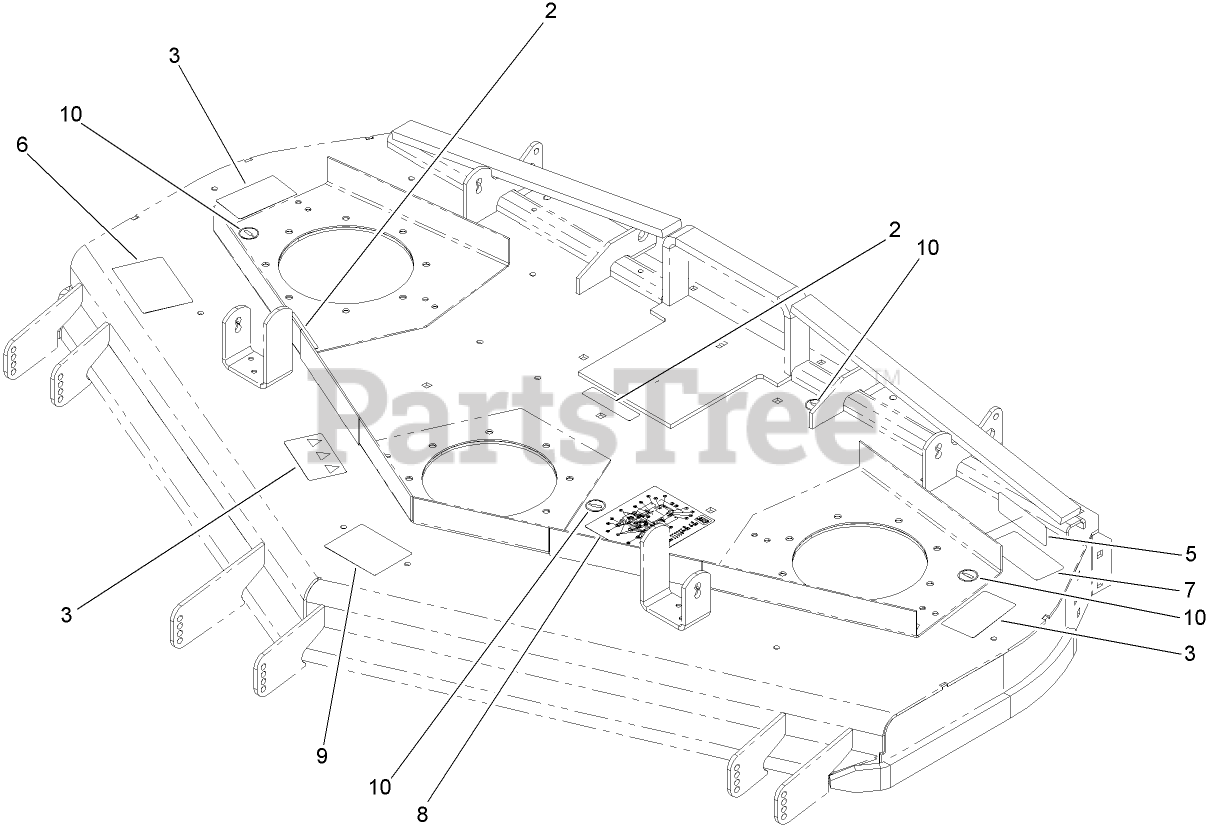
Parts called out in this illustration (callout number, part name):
2	DECAL-WARNING
3	DECAL-DANGER
6	DECAL
7	DECAL-TORQUE, BLADE BOLT
8	DECAL-SERVICE AID, BELT ROUTING CE
9	DECAL-ANTI SCALP
10	DECAL-GREASE
